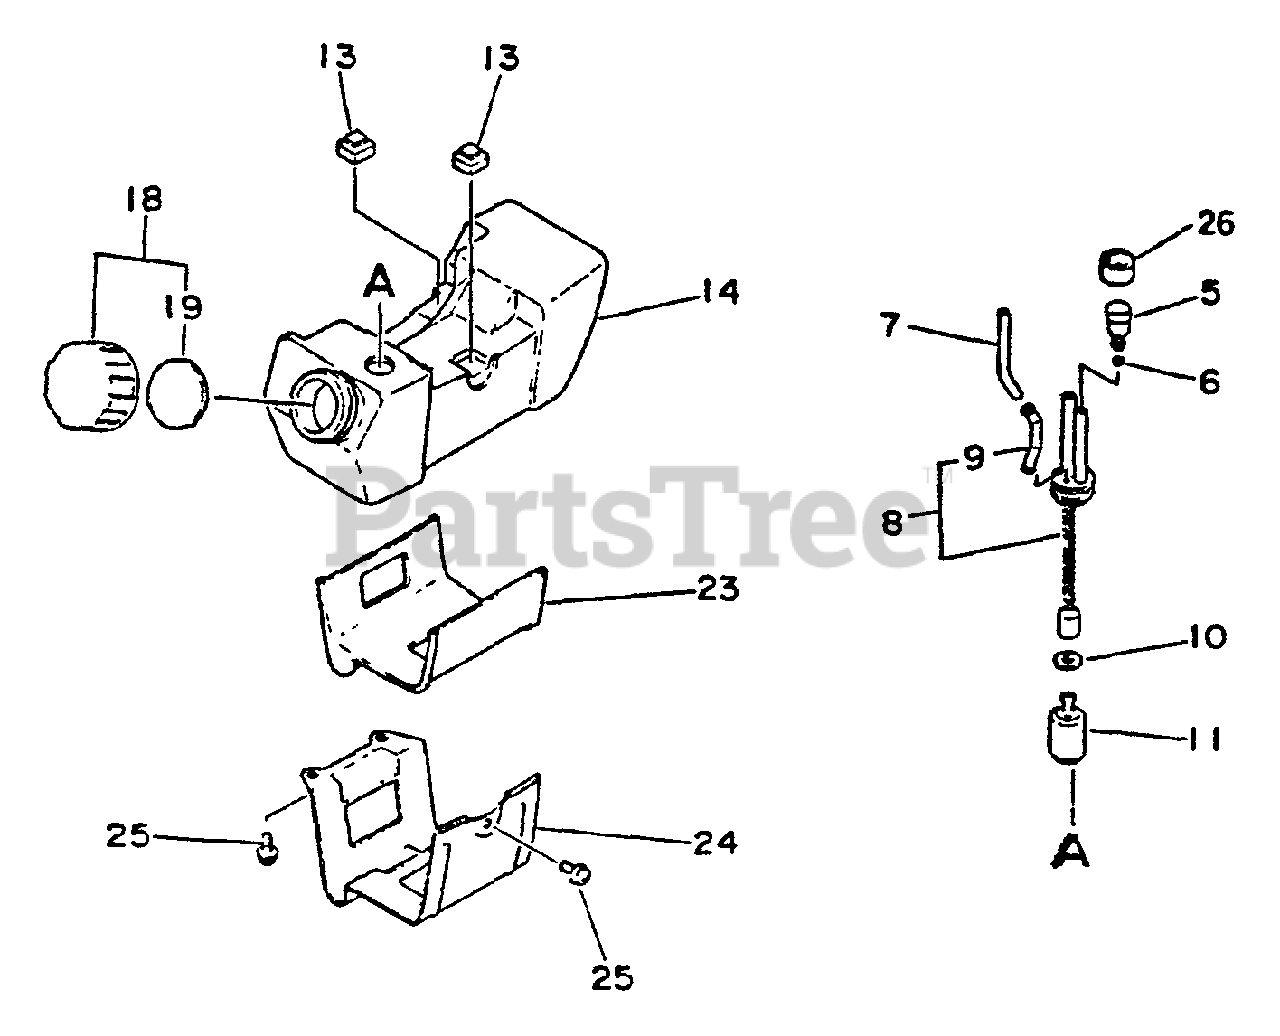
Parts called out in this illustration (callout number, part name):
5	VENT, FUEL TANK
6	CLIP - 5.5
7	PIPE - 3X6X45 -- CLEAR
8	FUEL SYSTEM KIT
9	CONNECTOR, PIPE
10	WASHER - 5
11	FILTER, FUEL
13	CUSHION
14	TANK, FUEL
18	CAP ASSY
19	GASKET, CAP
23	CUSHION
24	GUARD, FUEL TANK
25	SCREW - 5X10
26	COVER, VENT
